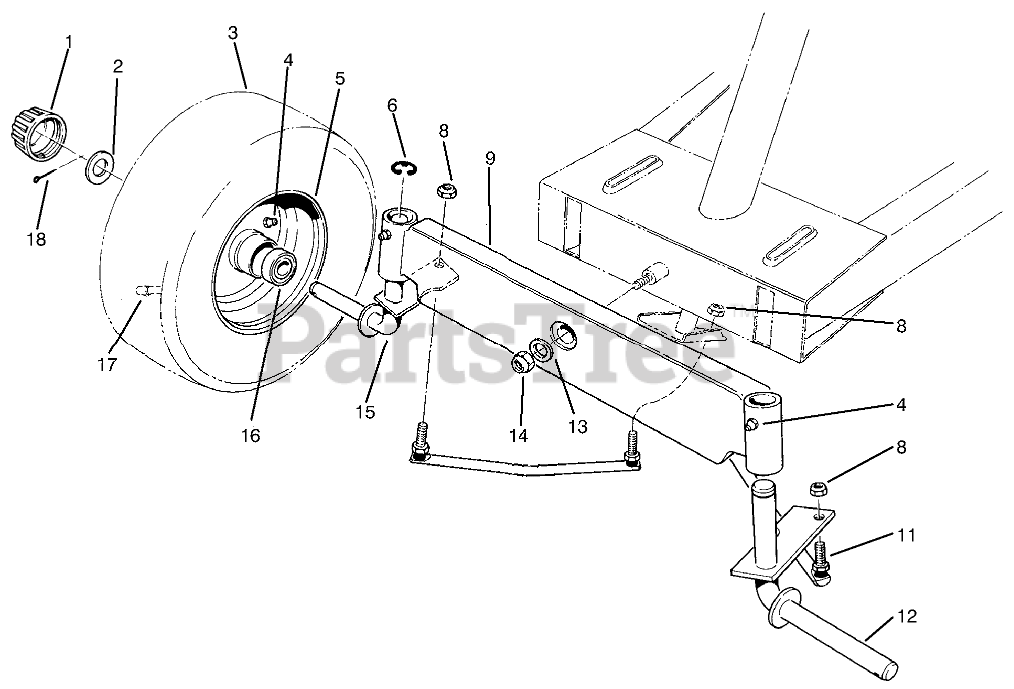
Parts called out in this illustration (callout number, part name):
1	CAP-HUB
2	WASHER-PLAIN
3	TIRE,PNEU.11X4.00X5
4	FITTING-GREASE
6	E-RING
8	NUT-LOCK
9	Axle-Front
11	TIE ROD ASM
12	WHEEL SPDLE WA LH (RED)
13	WASHER-FLAT
14	NUT-LOCK, NI
15	WHEEL SPDLE WA RH (RED)
16	BEARING-WHEEL
17	STEM-VALVE
18	PIN-COTTER
